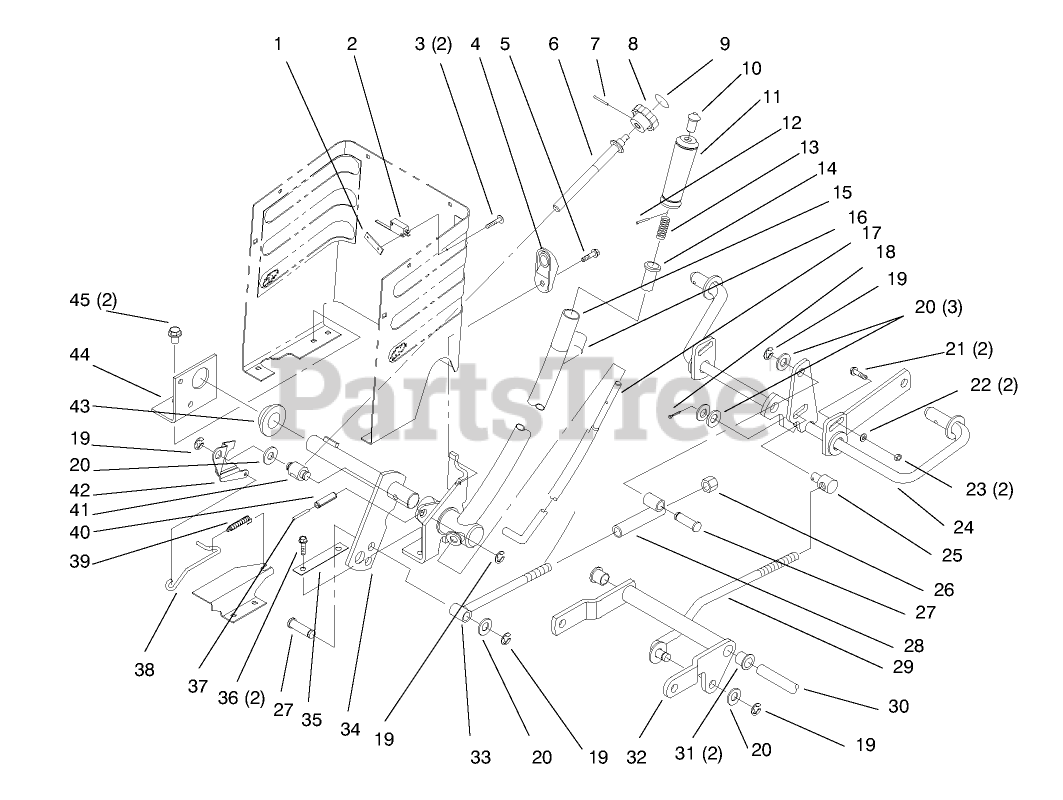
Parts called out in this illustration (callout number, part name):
1	NUT-SPEED
2	SWITCH-MICRO
3	SCREW-PPHTF
4	WEDGE - HOC
5	SCREW-HWH
7	PIN-SPIROL
10	TIP-ROD
11	GRIP-HANDLE
12	PIN-SPIROL
13	SPRING-COMPRESSION
14	RETAINER-SPRING
15	LEVER-LIFT
16	DECAL-LIFT
17	ROD-LEVER, LIFT
18	PIN-COTTER
19	RING-RETAINING, EXTERNAL
20	WASHER-FLAT
21	BOLT-CARR
22	WASHER-FLAT
23	NUT-LOCK, NI
24	SHAFT-GAGE
26	NUT-LOCK, NI
31	BUSHING-FLANGE
32	ARM-PIVOT
34	SHAFT-LIFT
36	SCREW-HWHTF
37	PIN-SPRING
38	ROD - HOC INDICATOR
39	SPRING - EXTENSION
40	PIN-ROLL
42	PLATE - HOC GAGE
43	BEARING-FLANGE
44	BRACKET-PIVOT, LINKAGE
45	SCREW-HWHTF
